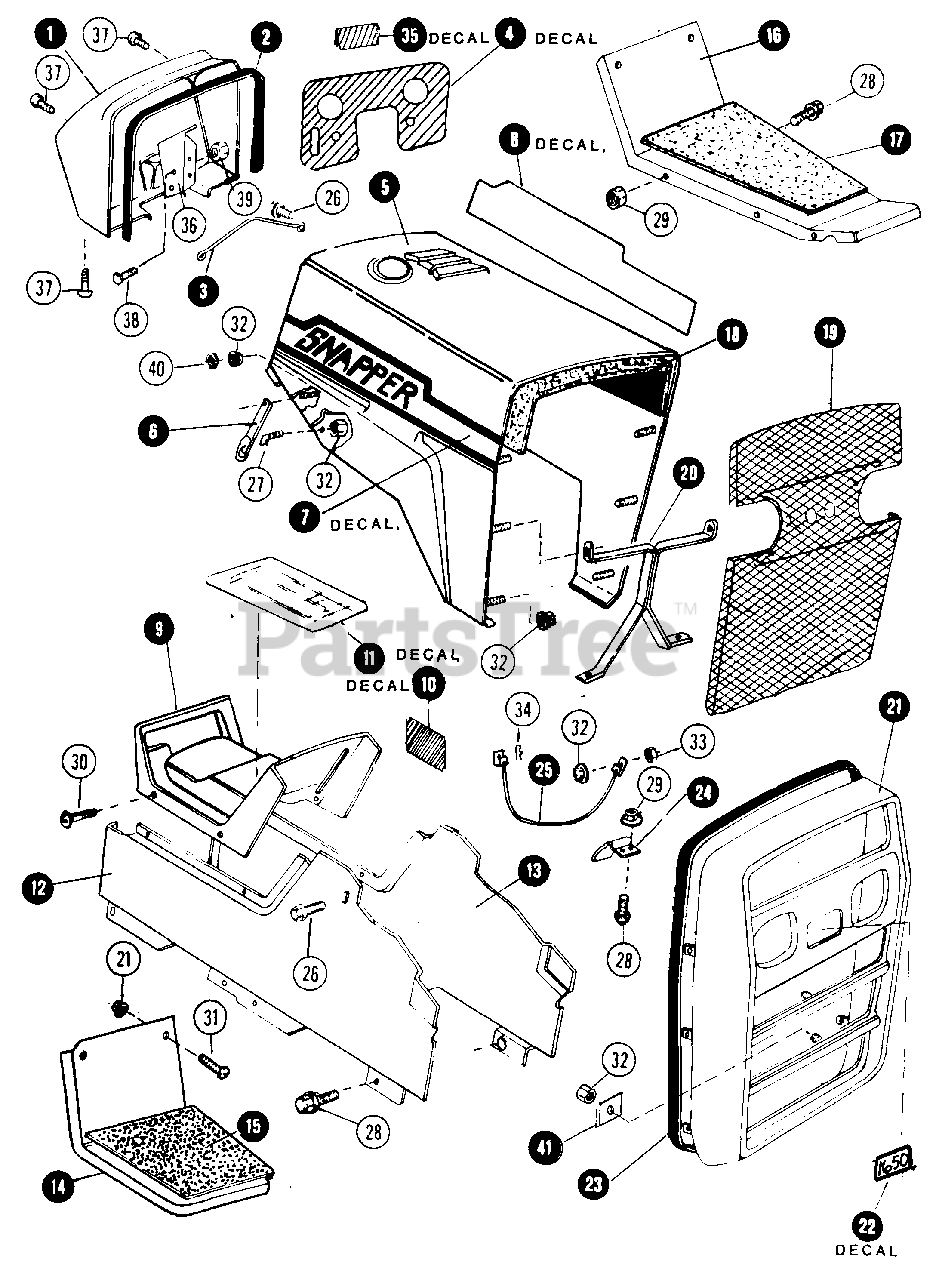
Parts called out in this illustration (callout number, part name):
1	COWL, INSTRUMENT DASH
2	TRIM, COWL MOLDING
3	REINFORCEMENT, COWL
4	DECAL, INSTRUMENT DASH
5	HOOD - PANEL
6	STRAP, HOOD RETAINER
7	DECAL, SNAPPER RIGHT SIDE HOOD
8	DECAL SNAPPER LEFT SIDE HOOD
9	PANEL CENTER ACCESS CONSOLE
10	DECAL, CAUTION
11	DECAL, CONSOLE - OPERATING INSTRUCTION
12	PANEL, RIGHT SIDE
13	PANEL, LEFT SIDE
14	PLATE, RIGHT STEP
15	TREAD, RIGHT PLATE
16	PLATE, LEFT STEP
17	TREAD, LEFT STEP PLATE
18	INSULATION, HOOD - PANEL
19	GRILLE - SCREEN ASSEMBLY
20	BRACE, HOOD
21	GRILLE - PANEL ASSEMBLY
22	DECALS 1650 SERIES IDENTIFICATION
23	TRIM, HOOD - GRILLE MOLDING
24	HINGE HOOD TILT
25	CABLE, HOLD TILT STOP
26	BOLT, 5/16F x 5/8 HEX FLANGE
27	LATCH, HOOD RETAINER STRAP
28	BOLT, 5/16C x 3/4 HEX FLANGE LOCK
29	NUT, 5/16C HEX FLANGE LOCK
30	SCREW, PAN HEAD 5/16C x 1/2
31	SCREW, 5/16C x 5/8 ROUND HEAD
32	NUT, 1/4C HEX FLANGE LOCK
33	NUT, 1/4C HEX LOCK
34	PIN, HAIR
35	DECAL REFUEL CAUTION
36	BRACKET, COWL MOUNTING L.H.
37	SCREW, 5/16C x 3/4 ROUND HEAD
38	BOLT 3/8C x 3/4 HEX
39	NUT 3/8C HEX FLANGE LOCK
40	WASHER, 1/4 FLAT
41	WASHER, GRILLE SCREEN PLATE
